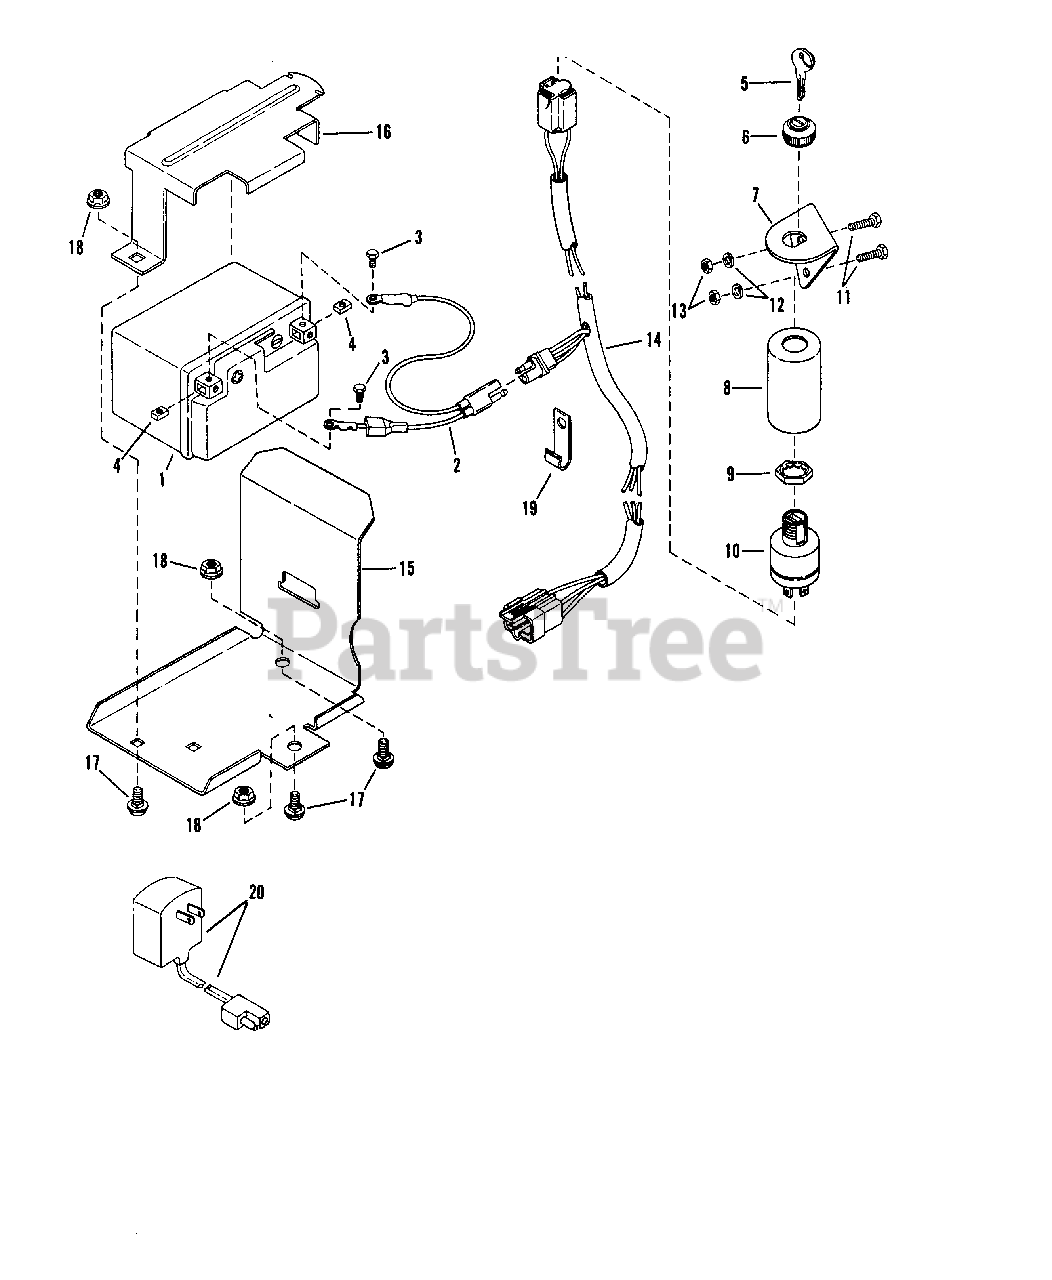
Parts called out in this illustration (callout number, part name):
1	KIT, Battery 12 Volt
2	HARNESS, Battery (For '88 & earlier, use with item 21)
3	SCREW, #10-24 x 1/2" Hex Head Cap
4	NUT, #10-24 Square
5	KEY, (Set of 2)
6	ASSEMBLY, Seal & Face Nut
7	BRACKET, Ignition Switch
8	COVER, Switch
9	NUT, 3/4-20 Lock
10	SWITCH, Ignition
11	SCREW, 1/4-28 x 1 3/8 Hex Head Cap
12	WASHER, 1/4 Internal Tooth Lock
13	NUT, 1/4-28 Hex
14	HARNESS, Wiring (For '88 & earlier, use with item 21)
15	BRACKET, Battery (Self-Propelled Models)('88 & earlier)
15	BRACKET, Battery (Push Models)
15	BRACKET, Battery (Self-Propelled Models) ('89 Models & Later)
16	COVER, Battery (Self-Propelled Models)
16	COVER, Battery (Push Models)
17	BOLT, 5/16-18 x 112" Carriage
18	NUT, 5/16-18 Hex Flange Lock
19	CLIP, Wiring
20	CHARGER, Battery (60 Hertz) ('86 & Earlier Models)
